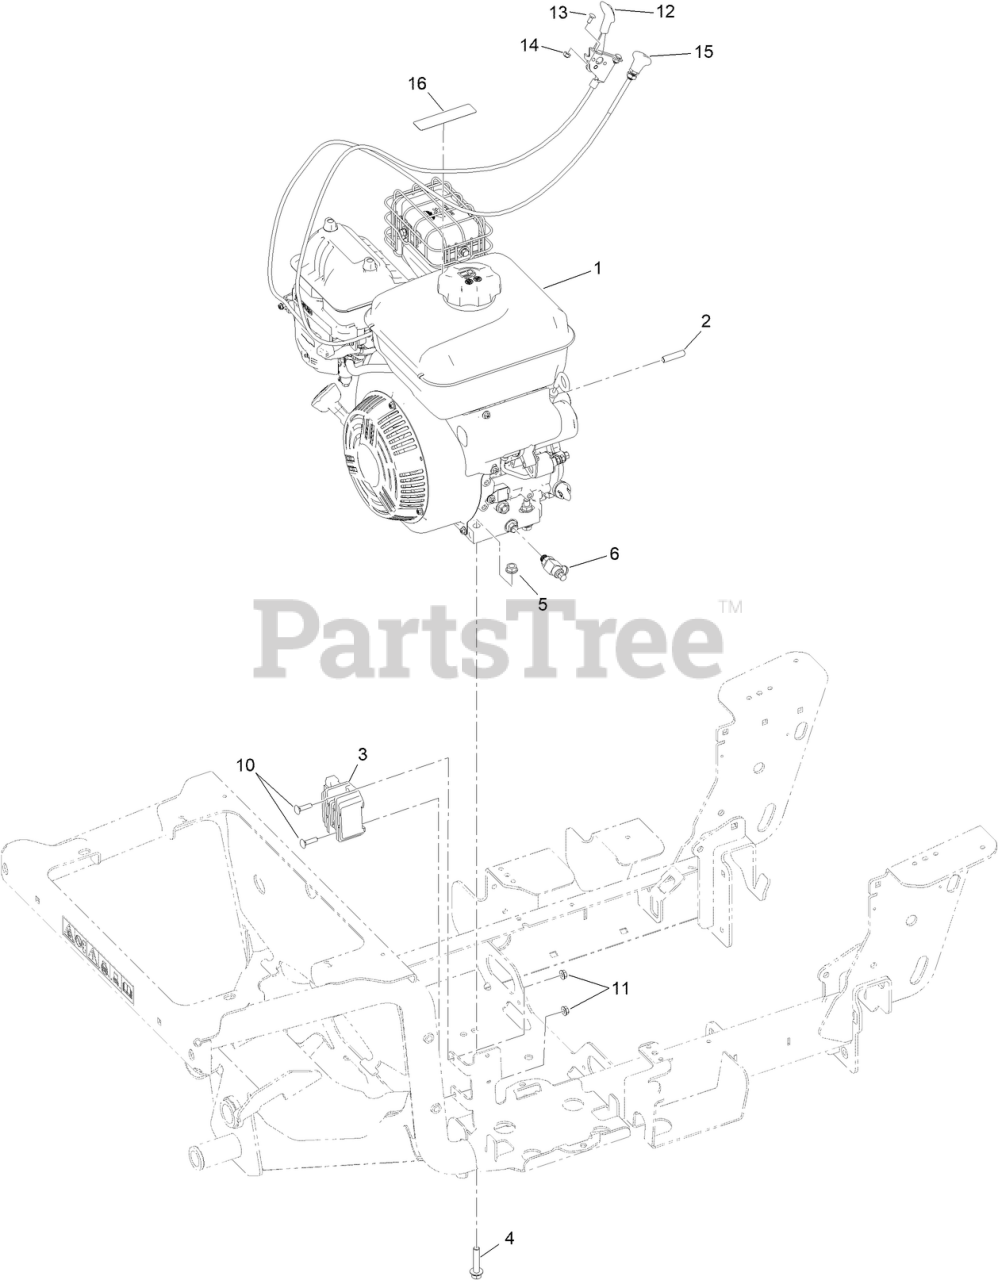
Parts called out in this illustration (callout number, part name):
1	Engine-Briggs, Bv307
2	KEY-SQUARE, 7MM
3	REGULATOR-TROMBETTA, 18A
4	SCREW-HHF
6	Valve-Drain, Oil
10	SCREW-CARR
12	CONTROL,THROTTLE
13	BOLT-CARR
14	NUT-LOCK, NI
15	Cable-Choke, Push/Pull
16	DECAL-ARRESTOR, SPARK
